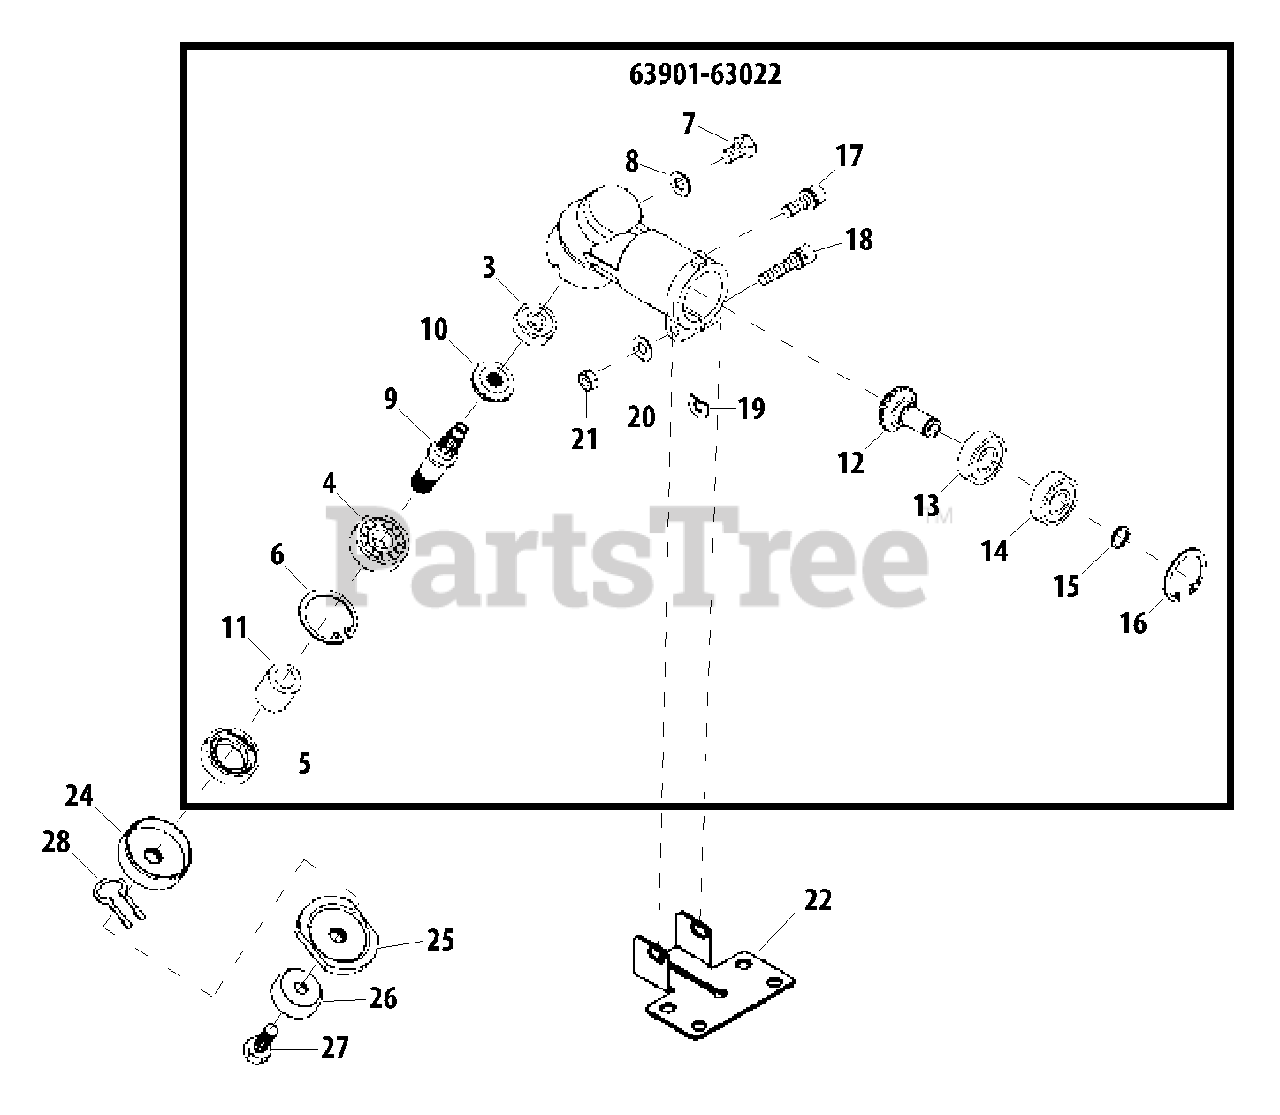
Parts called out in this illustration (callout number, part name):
3	BEARING, BALL - 626
4	BEARING, BALL - 6000
5	SEAL, OIL
6	RING, RETAINING - 26
7	BOLT - 6X10
8	WASHER
9	GEAR - SHAFT
10	GEAR - BEVEL
11	COLLAR
12	GEAR - SHAFT
13	BEARING, BALL - 608
14	BEARING, BALL - 608ZZ
15	RING, RETAINING
16	RING, RETAINING - 22
17	SCREW - 5X16
18	SCREW - 5X35
19	SHIM
20	WASHER - 5
22	CLAMP - LOWER
24	HOLDER - A
25	HOLDER B, REPLACES 22035-13251, REPLACES 22553-13250
26	GUARD
27	BOLT - 7X18 -- LEFT HAND
28	SLIDE CLIP
63901-63022	GEAR CASE ASSY
